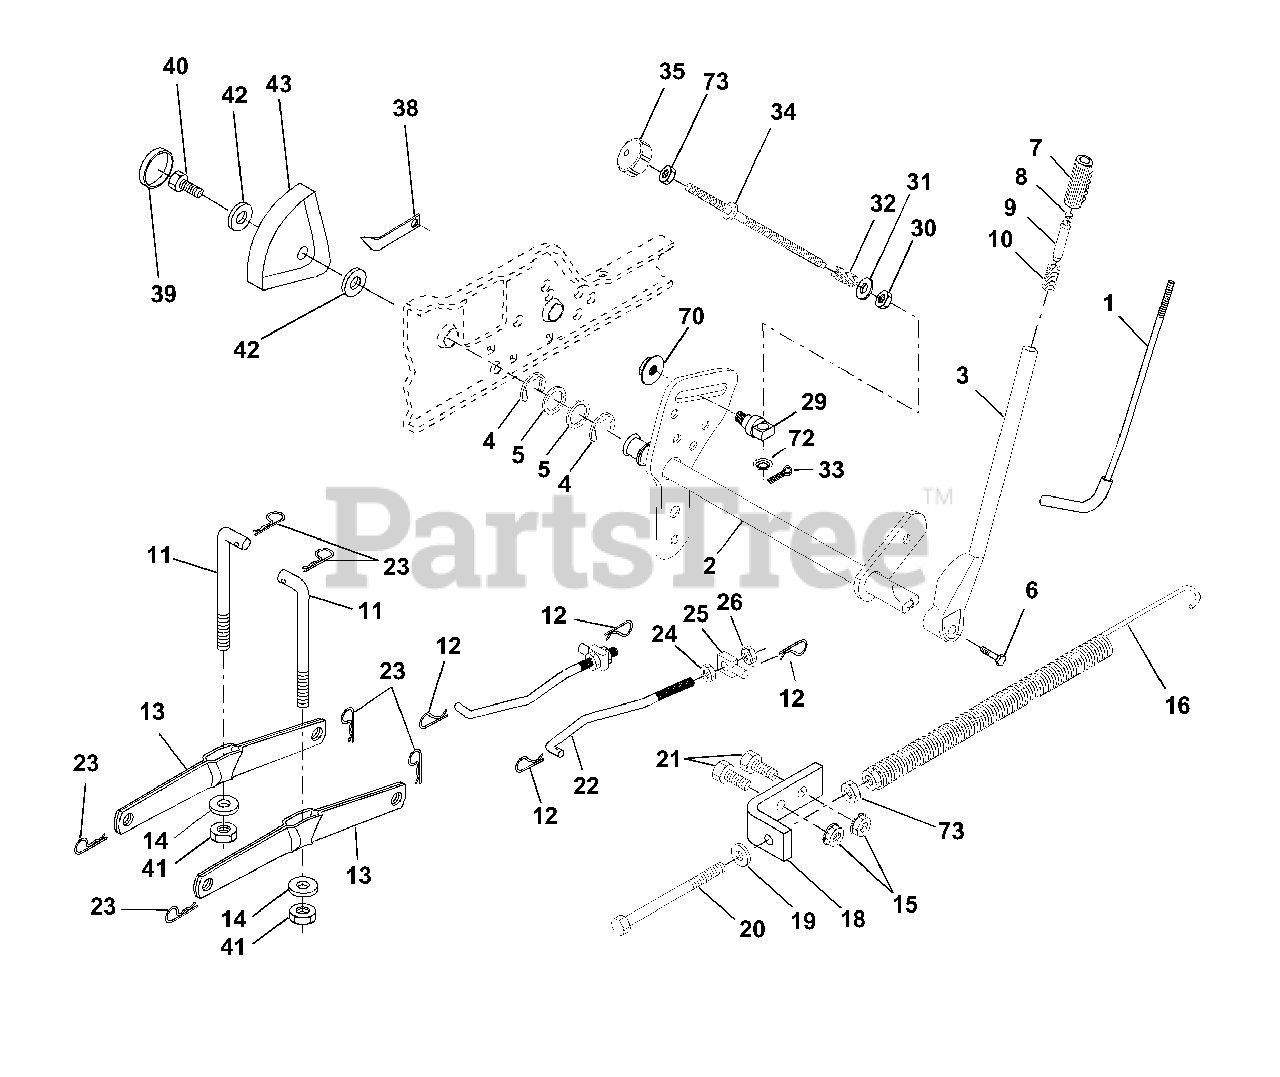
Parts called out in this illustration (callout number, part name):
1	Rod Asm., Lever
2	Shaft Asm., Lift Vgt
3	Lever Asm., Lift Rh
4	E-Ring Truarc #5133-87
5	Washer 29/32 x 1-1/4 x 16 Ga.
6	Bolt, Fin Hex 3/8-16 x 1-1/2
7	Grip, Handle Fluted
8	Button, Plunger
9	Plunger, Lever Lift
10	Spring 2-1/8"
11	Link Lift
12	Retainer, Spring
13	Arm, Suspension Vgt
14	Bearing, Pvt. Lift Tapered
15	Nut, Crownlock 3/8-16 Unc
16	Spring Asm., Assist Lift
17	Nut, Hex Jam 3/8-16 Unc
18	Bracket, Spring Assist
19	Washer 13/32 x 13/16 x 16 Ga.
20	Bolt, Adjust Spring Assist
21	Bolt, Fin Hex 3/8-16 x 1
22	Link, Front
23	Retainer, Spring
24	Nut, Jam Hex 1/2-13 Unc
25	Trunnion
26	Nut, Lock W/Wsh 1/2-13 Unc
29	Trunnion Inf. Height
30	Nut, Special
31	Washer 13/32 x 5/8 x 16 Ga.
32	Spring, Compression Inf Hgt
33	Pin, Cotter 3/32 x 1/2
34	Rod, Adj Lift
35	Knob, Inf 3/8-16 Unc
38	Pointer, Height Indicator
39	Plug, Hole
40	Screw 5/16-18 x 3/4
41	Nut, Crownlock 3/8-24
42	Washer 11/32 x 1-1/2 x 10 Ga.
43	Scale, Indicator Height
70	Nut, Hexflange Lock
72	Nut, Push Phos & Oil
73	Nut Hex Jam 3/8-16 Unc
